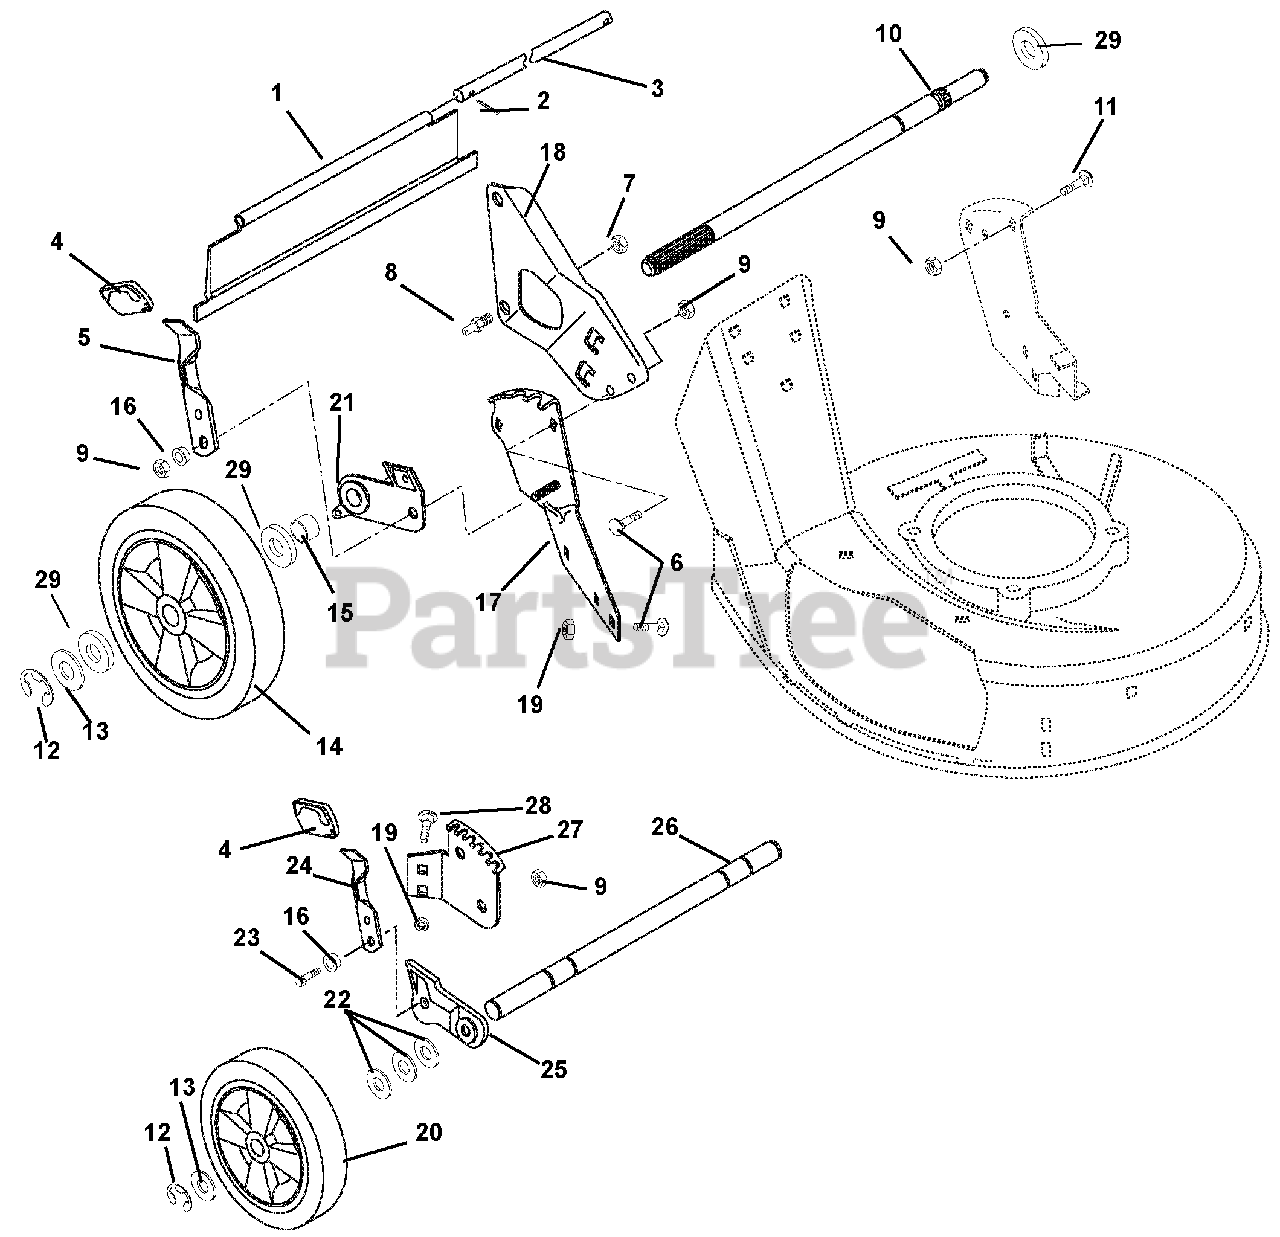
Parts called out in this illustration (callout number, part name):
1	Rear Protective Guard, Self Propelled
2	Pin, Cotter .06 x .50
3	Rod
5	Lever, Height Adjustment
6	Bolt, Round Head Square Neck .31-18 x .62
7	Nut, Locking Center .38-16
8	Handlebar Stud
9	Nut, Locking-Top-Flange Center .31-18
10	Rear Axle
11	Bolt, Round Head Square Short Neck .31-18 x 1.00
12	Ring, Retaining External .50 x .042
13	Washer, Flat Steel .505 x .88 x .072
14	Wheel, Left Hand Rear
14	Wheel, Right Hand Rear
14	Tire Skin 10 x 2.00
14	Tire, Rear 10 x 1.75
14	Kit, Rear Wheel Replacement
15	Spacer Tube
16	Bushing, Flange .312 x .50 x .344 x .88
17	Rear Quadrant-Left Hand
17	Rear Quadrant-Right Hand
18	Bracket, Handlebar Mounting-Right Hand
18	Bracket, Handlebar Mounting-Left Hand
19	Nut, Locking Top Flange .31-18
20	Wheel, Front
21	Rear Adjuster Bracket-Left Hand
21	REAR BRACKET AND BEARING ASSY RH
22	Washer, Flat Steel .520 x .827 x .062
23	Bolt, Hex .31-18 x 1.00 Grade 5
24	Lever, Front Height Adjustment
25	Left Hand Bracket Assembly
25	Right Hand Bracket Assembly
26	Front Axle
27	Front Quadrant, Left Hand
27	Front Quadrant, Right Hand
28	Bolt, Round Head Square Neck .31-18 x .50 Grade 5
29	Spacer .531 x 1.00 x .195
